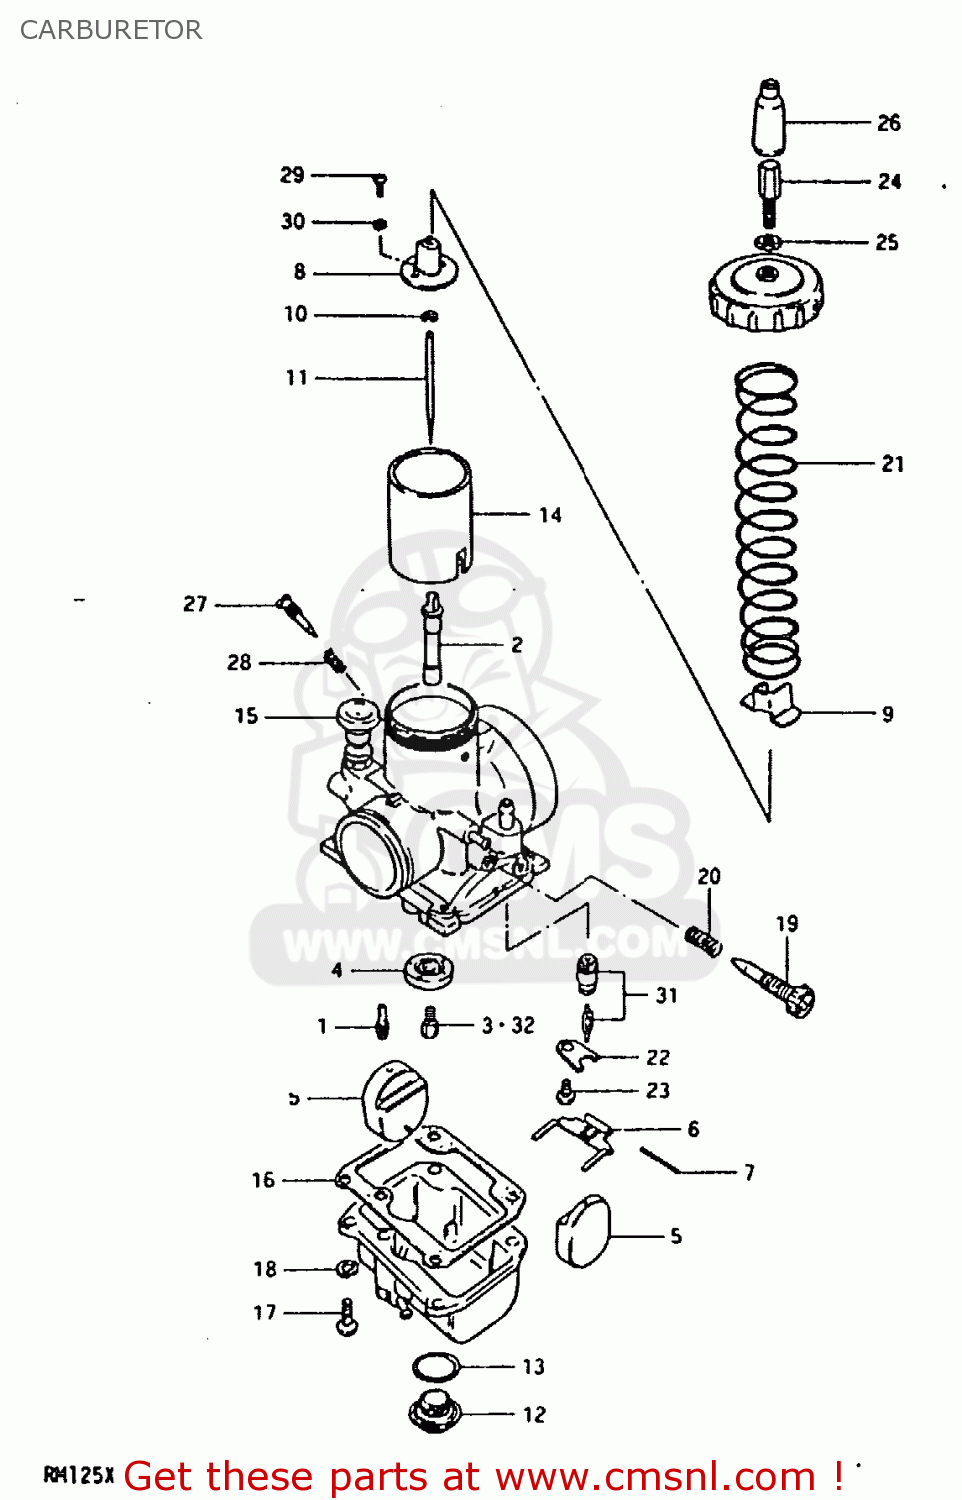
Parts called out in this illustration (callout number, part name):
1	JET
2	JET,NEEDLE
3	JET,MAIN(230)
4	RING,MAIN JET FIXING
5	FLOAT
6	ARM,FLOAT
7	PIN,FLOAT
8	CONNECTOR
9	COVER,HOLDER
10	CLIP
11	NEEDLE,JET
12	PLUG
13	O RING(D:1.5,ID:19.5)
14	VALVE,THROTTLE
15	VALVE ASSEMBLY,STARTER
16	GASKET,FLOAT CAHMBER (NAS)
17	SCREW
18	LOCK WASHER
19	SCREW,THROTTLE STOP
20	SPRING
21	SPRING,THROTTLE VALVE RETURN
22	PLATE
23	SCREW 4X6
24	ADJUSTER,CABLE
25	NUT
26	CAP,CABLE ADJUSTER
27	SCREW,PILOT AIR
28	SPRING
29	SCREW
30	LOCK WASHER
31	VALVE ASSEMBLY,NEEDLE
32	JET
